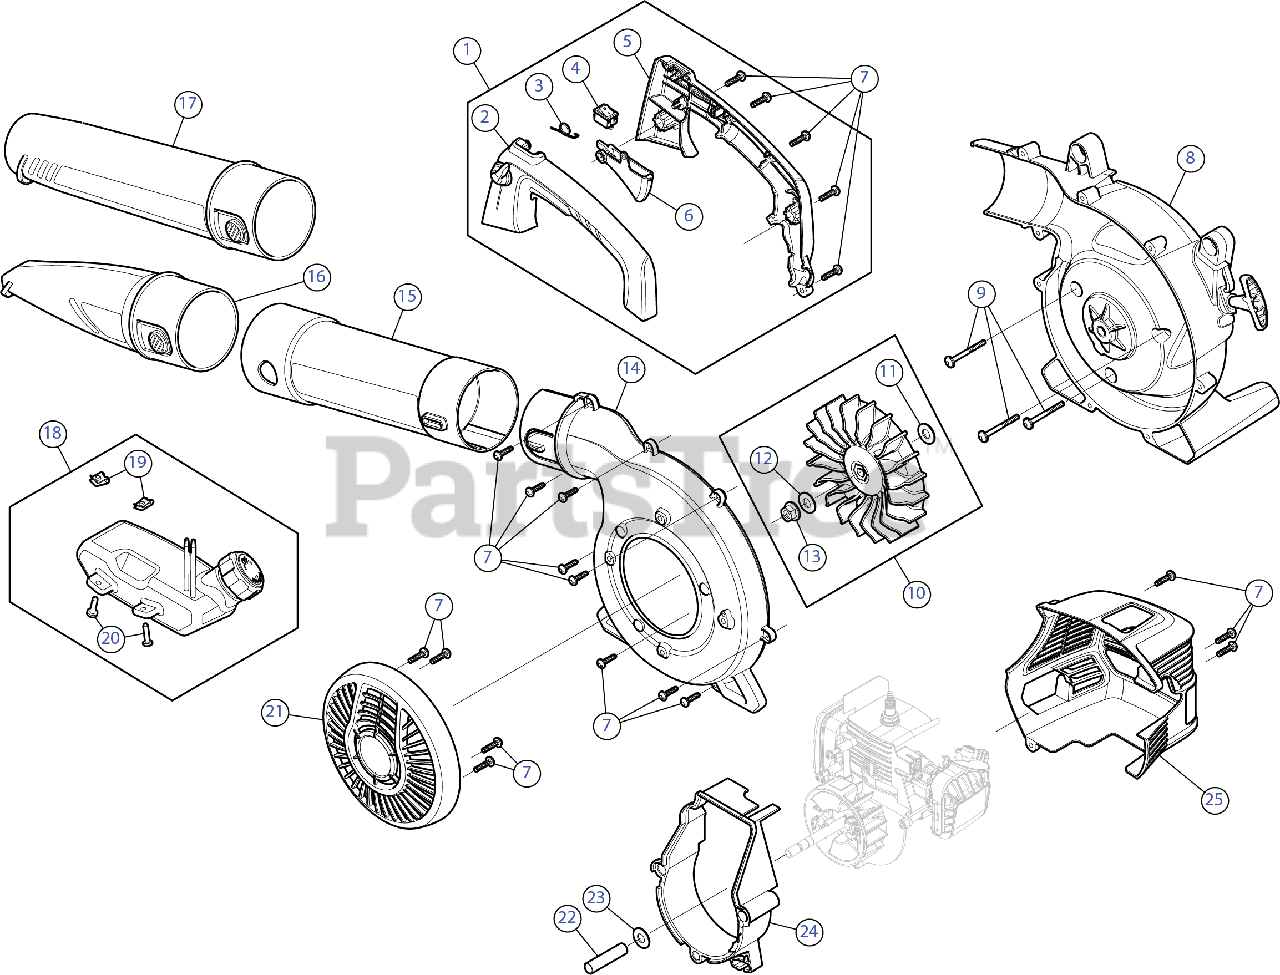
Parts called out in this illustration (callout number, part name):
1	HANDLE ASSEMBLY
2	HANDLE (LH)
3	SPRING TRIG
4	MOMENTARY SWITCH ON/OFF
5	HANDLE (RH)
6	THROTTLE TRIGGER
7	SCREW 8-16 x 3/4
8	IMPELLER HOUSING ASSEMBLY (INNER)
9	SCREW 10/32
10	IMPELLER ASSEMBLY
11	FLAT WASHER
12	LOCK WASHER
13	NUT 3/8-24
14	IMPELLER HOUSING ASSEMBLY (OUTER)
15	TUBE UPPER
16	NOZZLE
17	TUBE LOWER
18	FUEL TANK ASSEMBLY
19	NUT, TINNERMAN U-T
20	SCREW:10-6 x .75
21	INTAKE COVER
22	SPACER
23	FLAT WASHER
24	ENGINE ADAPTER
25	ENGINE COVER
